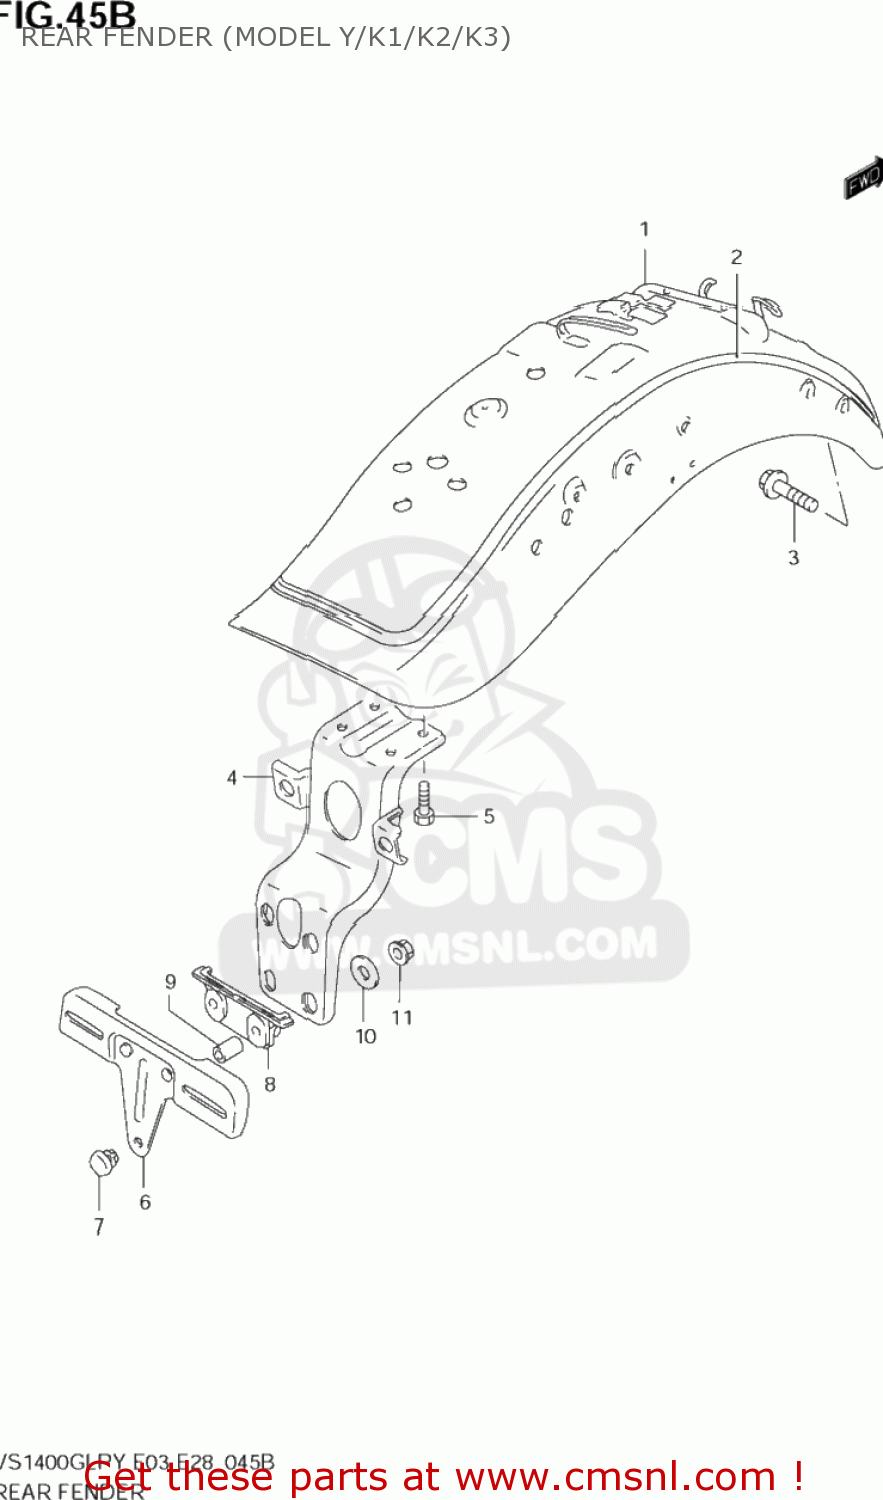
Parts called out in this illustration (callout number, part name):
1	FENDER ASSY,RR
2	TAPE SET,RR FENDER
3	BOLT
4	BRACKET,RR COMBINATION LAMP
5	BOLT
6	PLATE,REAR LICENSE
7	CUSHION
8	CUSHION,RR LICENSE PLATE
9	SPACER(5.5X8X14.3)
10	WASHER(5.5X20X1.2)
11	NUT
